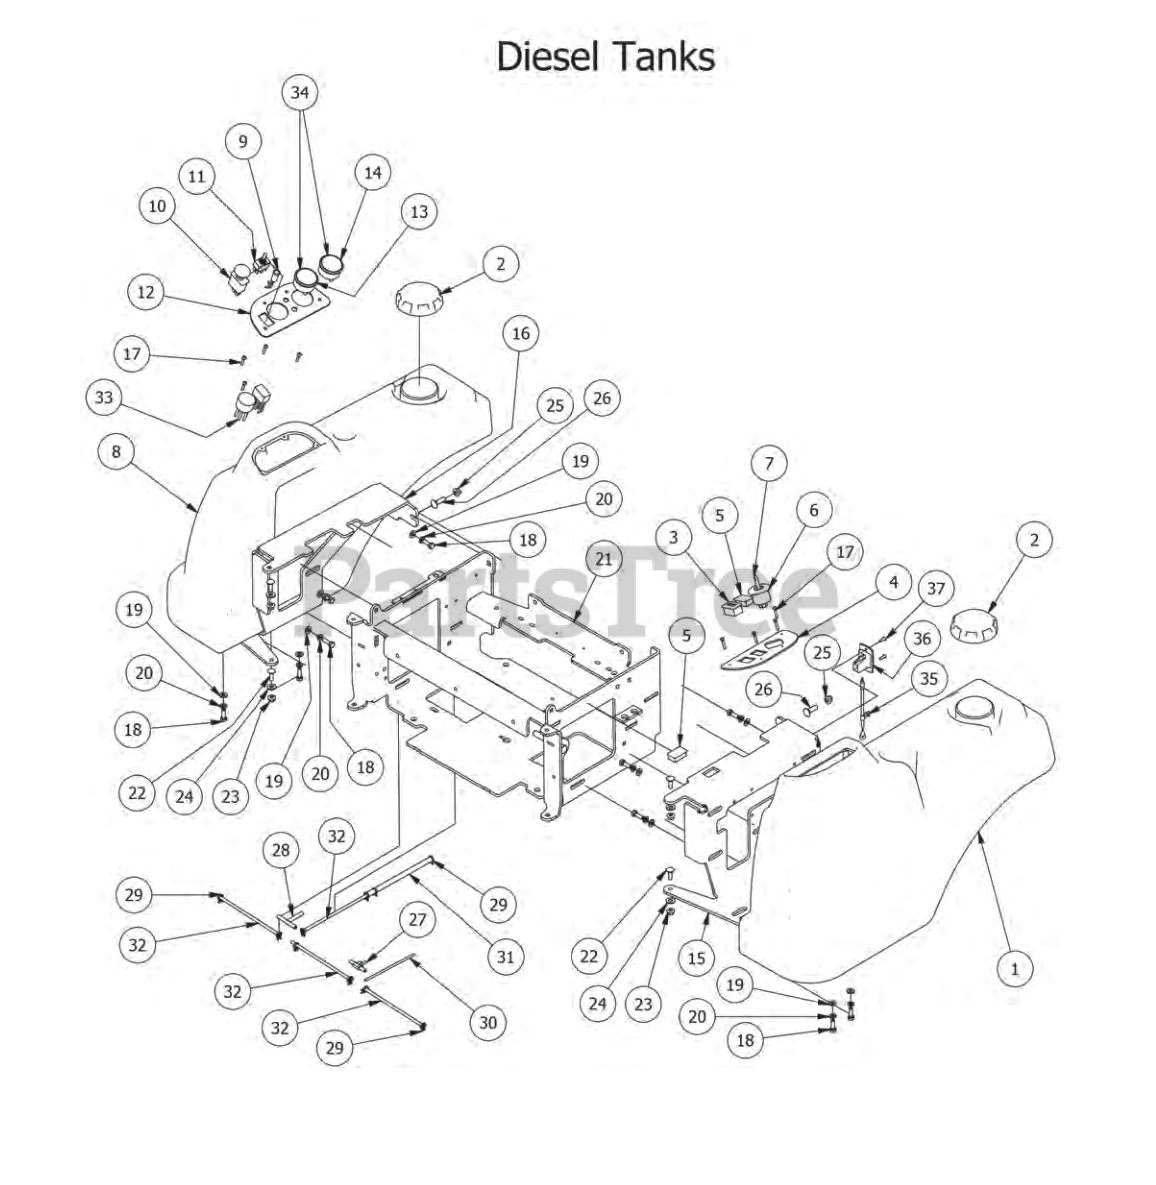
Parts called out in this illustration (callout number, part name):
1	Left Fuel Tank with Fender
2	Diesel Fuel Cap-3.5 inch Neck
3	Hour Meter
4	Control Panel (Left)
5	Light Plug
6	Ignition Switch
7	Ignition Key
8	Right Fuel Tank with Fender
10	PTO Engager
11	Deck Lift Joystick
12	Diesel Control Panel Right 2012
13	2" Water Temperature Gauge
14	2" Oil Pressure Gauge
15	Left Tank Support
16	Right Tank Support
17	10-32 x 1 Button Head Bolt
18	5/16" x 1" Bolt
19	5/16" Flat Washer
20	5/16" Lock Washer
21	Diesel Seat Frame
22	5/16" x 1" Carriage Bolt
23	5/16" Flange Nut
24	360 ID Plastic Washer
25	3/8" Nylock Flange Nut
26	3/8" x 1 1/4" Carriage Bolt
27	Brass fuel line T
28	fuel line T
29	1/4 fuel clamp
30	3/16 Fuel Line
31	5/16" fuel line hose
32	1/4" fuel line hose
33	Wiring Harness
34	Pigtail-2" Faria Gauge -2012 & up (Used For the water and Oil Gauges)
35	2015 Seat Latch Cable
36	2015 Seat Latch Toggle
37	3/16 Rivet
